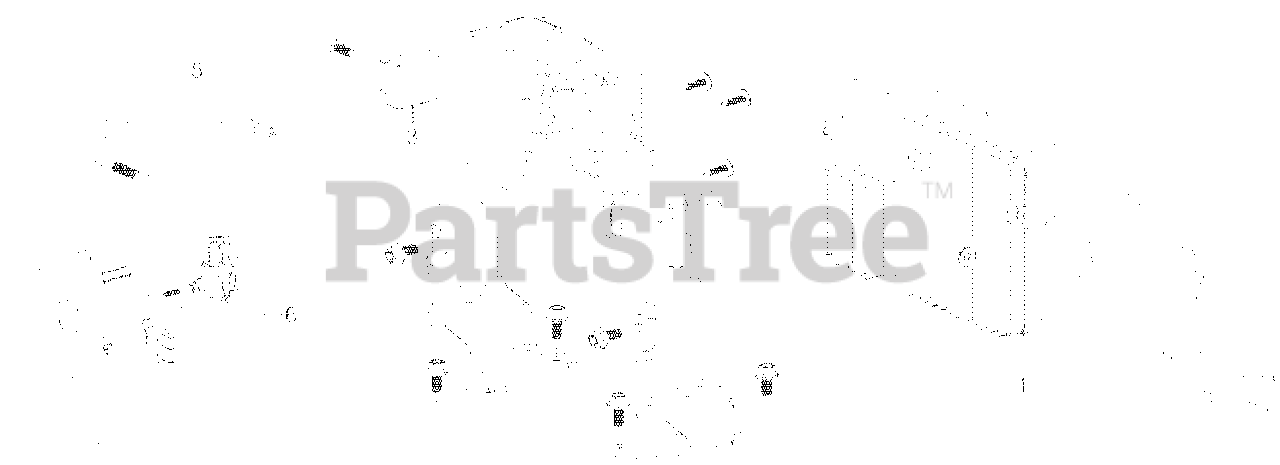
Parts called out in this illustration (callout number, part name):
1	INVERTER ASSY.
3	RECTIFIER BRIDGE
5	CHOKE CABLE
6	COMBINATION SWITCH
